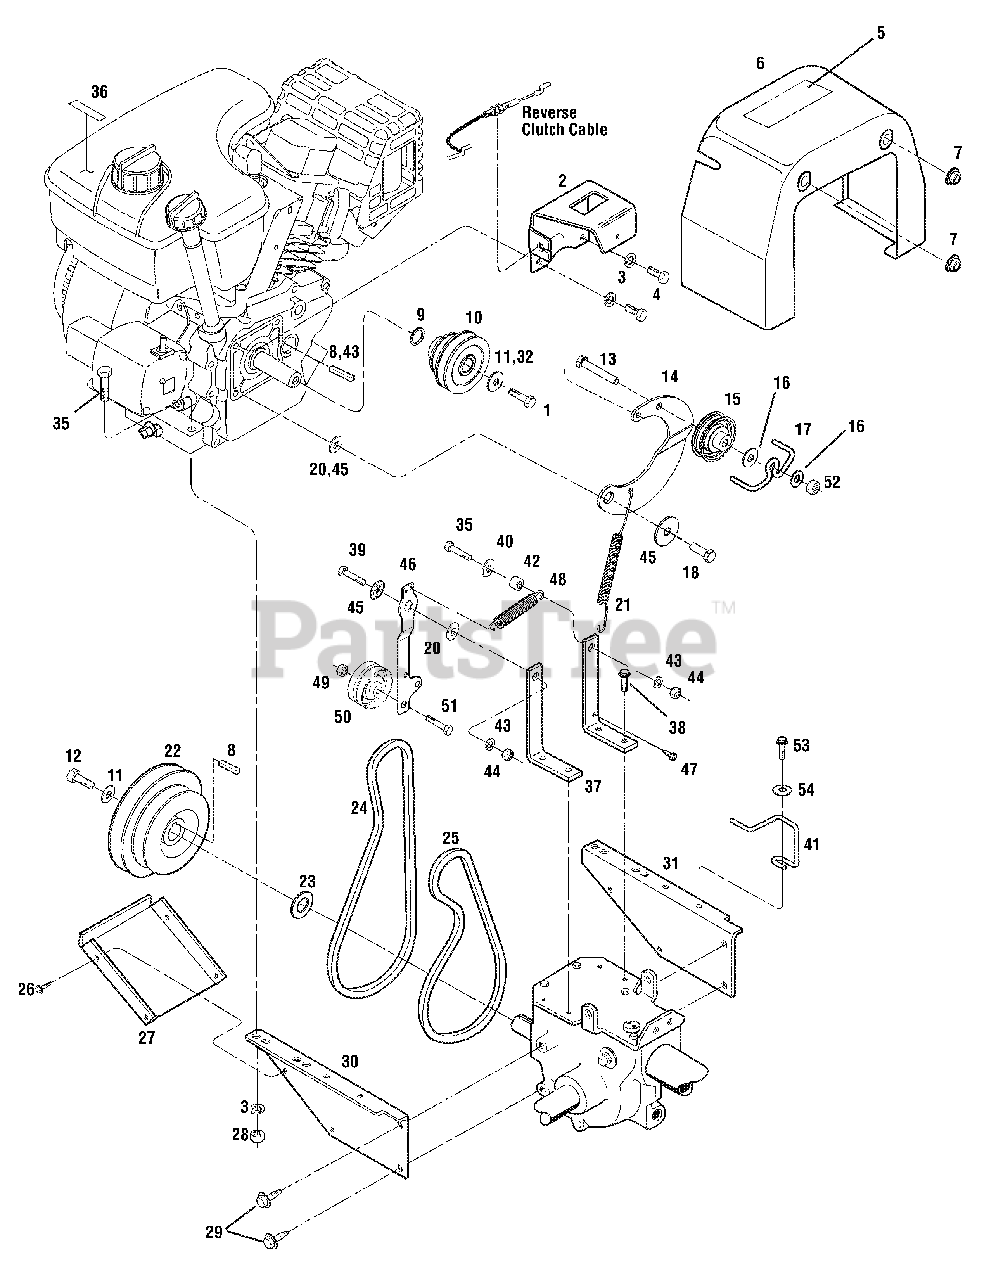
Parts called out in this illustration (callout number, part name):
1	Screw, 3/8-24 x 1.75
1	Screw, 5/16-24 x 1.125
4	Hex Hd. Screw, 5/16-24 x 1/2
5	Decal, Hot Surfaces/Belt Warning
7	Flange Lock Nut, 5/16-18
8	Key, 3/16 x 1-1/2
10	Pulley, Engine Drive
11	Belleville Washer
12	Hex Hd. Screw, 5/16-24 x 1-1/8
13	Hex Hd. Screw, 5/16-18 x 2
14	Reverse Idler Arm
15	Pulley, Reverse Idler
16	Flat Washer, 5/16
17	Belt Guide, Wire Formed
18	Hex Head Screw, 5/16-24 x 1
19	Washer, Shoulder
20	Washer, Flat, 1-1/8
21	Spring, Reverse Return
22	Transmission Pulley
23	Support Washer
24	Reverse Clutch Belt
25	Forward Clutch Belt
26	Self-tapping Screw, #10-32 x 1/2,
28	Hex Flange Nut, 5/16-18
29	Hex Flange Screw, 5/16-18 x 3/4
32	Bell Washer
35	Hex Hd. Screw, 5/16-18 x 2-1/4
36	Decal, Stabilization
37	Mounting Bar
38	Hex Flange Screw, 5/16-18 x .75
39	Hex Hd. Screw, 5/16-18 x 1-1/2
40	Flat Washer, 5/16'
41	Belt Guide, Pony
42	Pivot Bushing
43	Key, .188 x 1.75
44	Hex Nut, 5/16-18
45	Washer, Shoulder
47	Screw, self tapping, #10-24
49	Hex Locknut, 5/16-18
50	Idler Pulley, Forward
51	Screw, 3/8-16 x 1-3/4
52	Hex Lock Nut, 5/16-18
53	Screw, 1/4-20 x 3/4
54	Flat Washer-1/4
